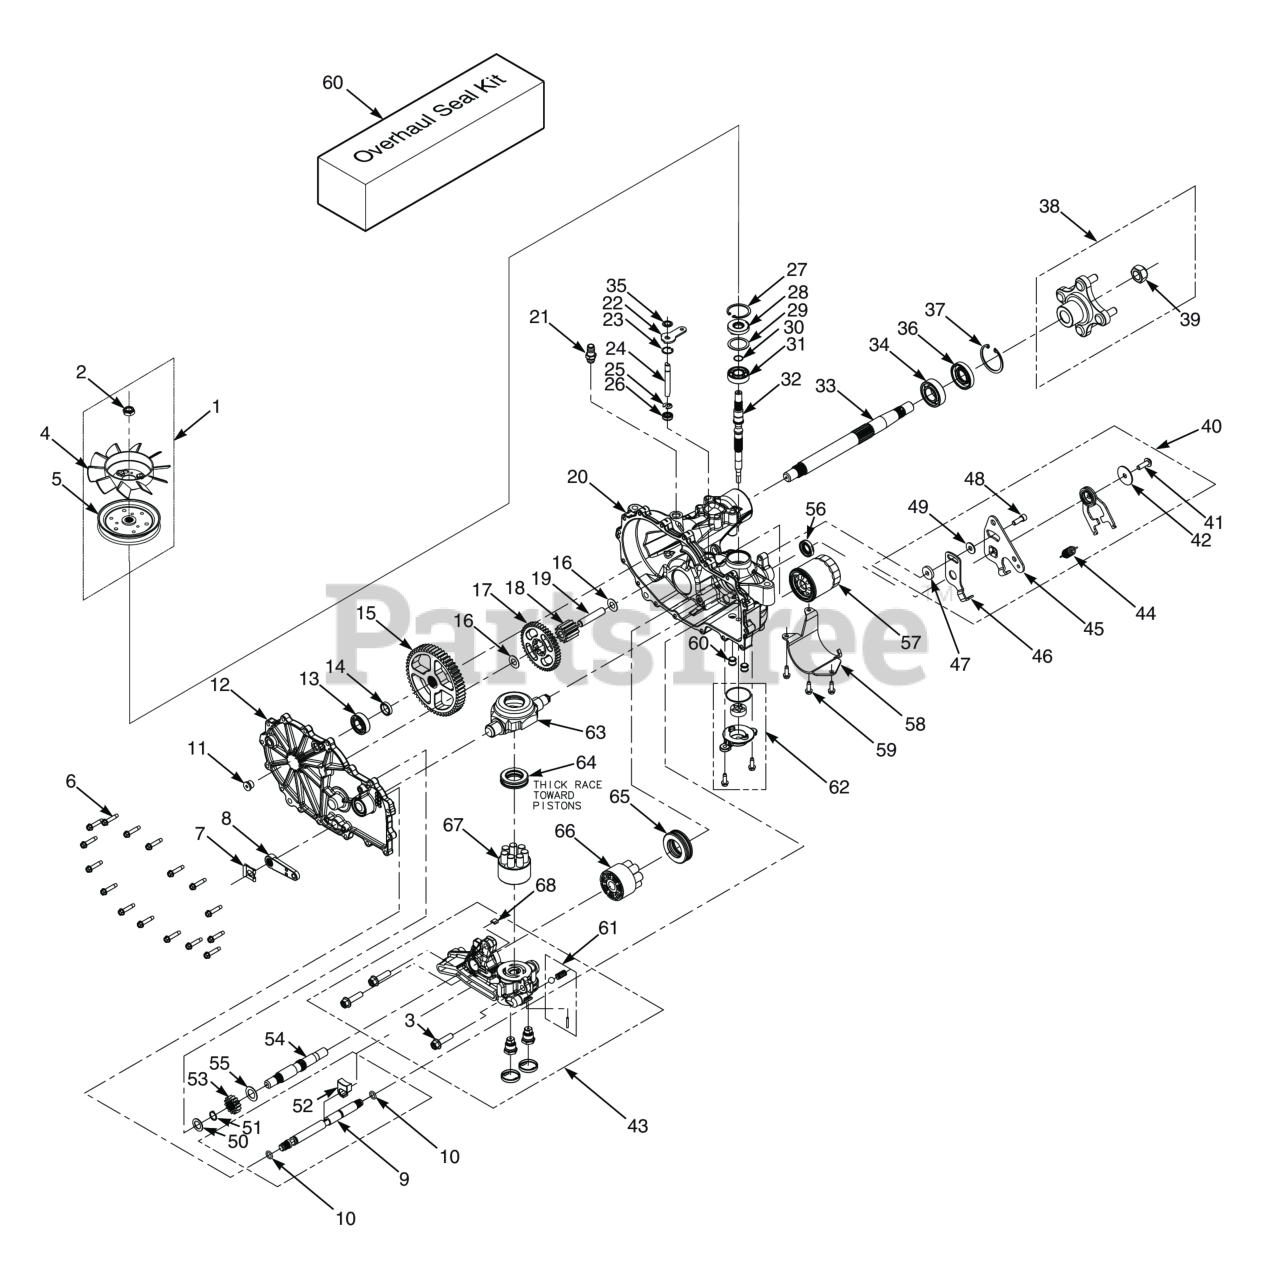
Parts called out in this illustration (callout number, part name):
1	Kit, Fan & Pulley
2	Nut, Hex Locking 1/2-20
3	Screw, Hex Flange Head 3/8-16 x 1-1/2"
4	Fan (order through Hydro-Gear)
5	Pulley, Cupped 4-1/2" Dia.
6	Clip, Brake Lever (order through Hydro-Gear)
7	Clip, Retaining
8	Lever, Brake (order through Hydro-Gear)
9	Shaft, Brake
10	O-Ring, -111 x .103 x 424
11	Straight Thread Plug
12	Kit, Side Cover RH
12	Kit, Side Cover LH
13	Bearing, Ball .75 x 40 x 12
14	Spacer, .75 x 1.0 x .257
15	Gear, 54T
16	Washer, .5 x 1.0 x .03
17	Gear, 45T
18	Gear, 11T Steel
19	Jackshaft Pin
20	Kit, Housing RH
20	Kit, Housing LH
21	Fitting, Transmission
22	Arm, By-Pass
23	R i n g , Retaining .750 Internal
24	Rod, By-Pass
25	Ring, .Retaining .375 External
26	Seal, Lip .375 x .75 x .25
27	R i n g , Retaining 2.06 Internal
28	Seal, Lip 17 x 40 x 7
29	Washer, 1.23 x 1.56 x .04
30	Ring, Retaining Wire
31	Bearing, Ball 17 x 40 x 12 Open
32	Shaft, Input
33	Kit, Shaft, Axle
34	Bearing, Ball 1.0 x 52 x 15 Open
35	Ring, Retainging .375 External
36	Seal, Lip 25 x 52 x 10 TC Gray
37	R i n g , Retaining 2.06 Internal
38	Hub Kit
39	Nut, Hex Locking 3/4-16
40	Kit, RTN Bi-Directional (Left Side)
41	Bolt, Hex Head Cap Screw 5/16-24 x 1" Patch
42	Washer, .343 x 1.5 x .062
43	Kit, Center Section RH
43	Kit, Center Section LH
44	Spring, Extension, RTN - 44lbs
45	Arm, Control
46	Arm, Neutral (Right Side)
46	Arm, Neutral (Left Side)
47	Spacer, .320 x 1.005 x .179
48	Bolt, Hex Head Cap Screw 5/16-24 x 1" Patch
49	Washer, 7/16 x 7/8 OD x .06 HT
50	Washer, HT .62 ID x 1.0 OD x .05 Thick
51	Ring, Retaining .625
52	Pawl, Brake
53	Gear, 14T Steel
54	Shaft, Motor
55	Washer, .72 x 1.16 x .04
56	Seal, Lip 18 x 32 x 7
57	Filter, Oil
58	Guard, Filter (Right Side)
59	Bolt, 1/4-20 x 3/4"
60	Seal Kit
61	Kit, Charge Relief
62	Kit, Charge Pump
63	Trunnion, Swashplate
64	Ball Thrust Bearing
65	Thrust Ball Bearing Assembly
66	Kit, Motor Cylinder Block
67	Kit, Cylinder Block
68	Plate, By-Pass
69	Kit, Charge Relief
